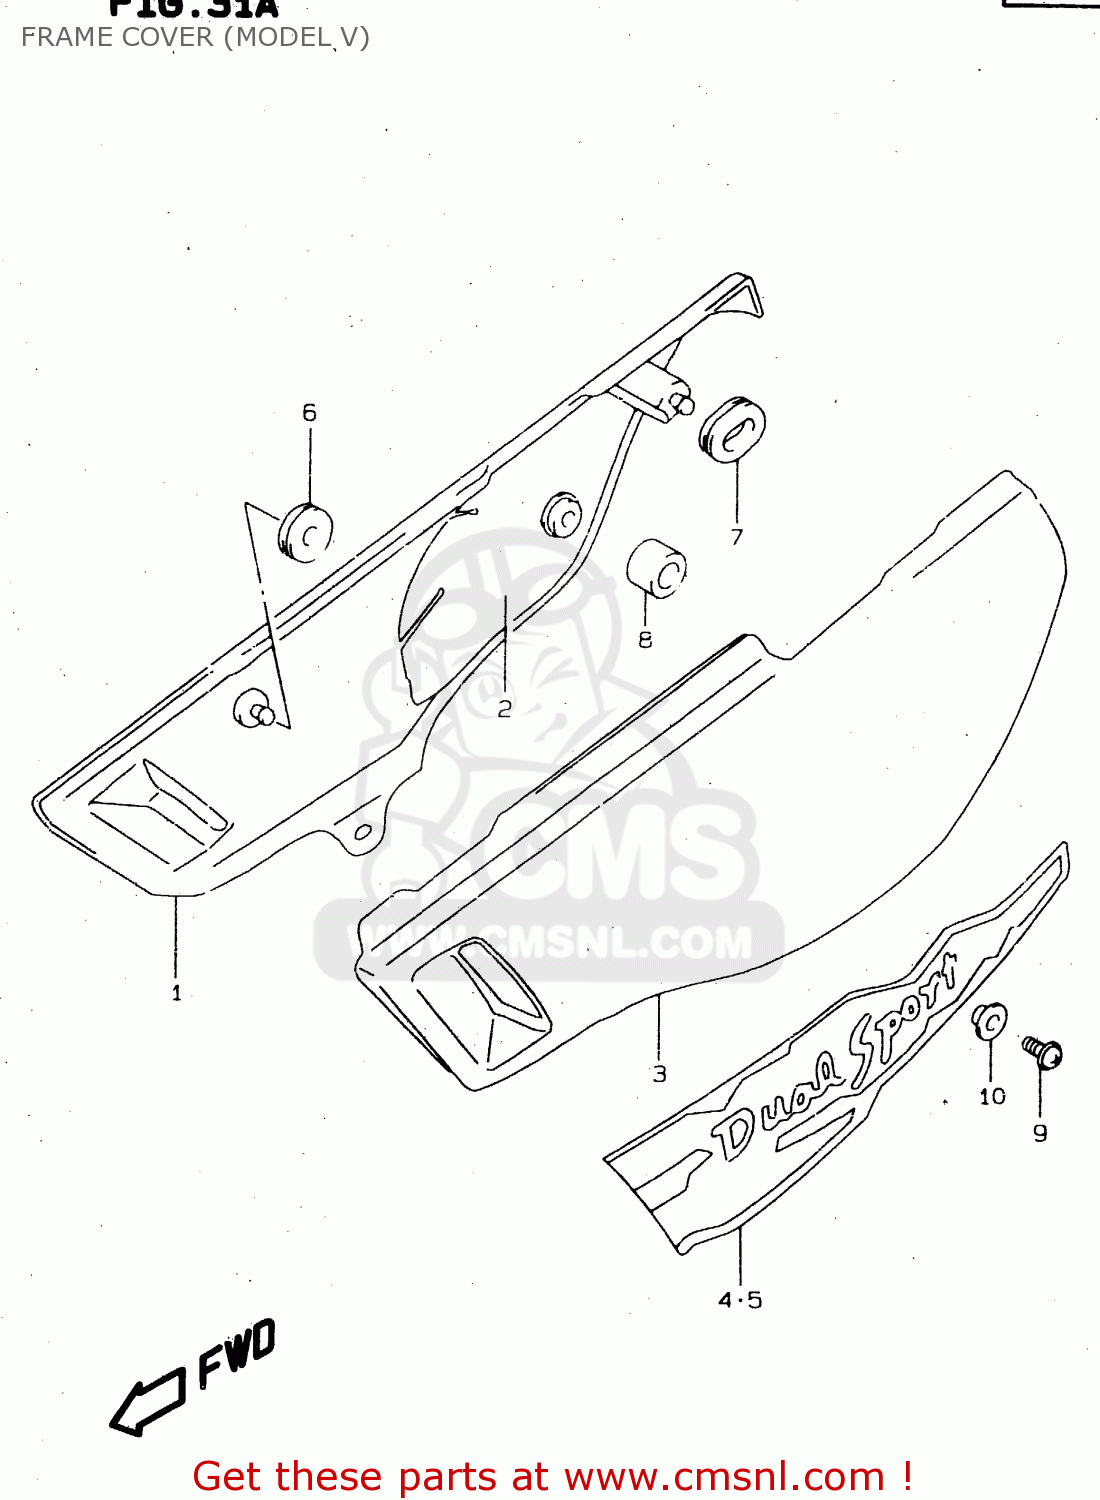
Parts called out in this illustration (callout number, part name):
1	COVER,FRAME,R(WHITE)
2	SHIELD,FRAME COVER,R
3	COVER FRAME,L(
4	TAPE, RH
5	TAPE, LH
6	CUSHION
7	CUSHION
8	CUSHION
9	SCREW(6X16)
10	WASHER
